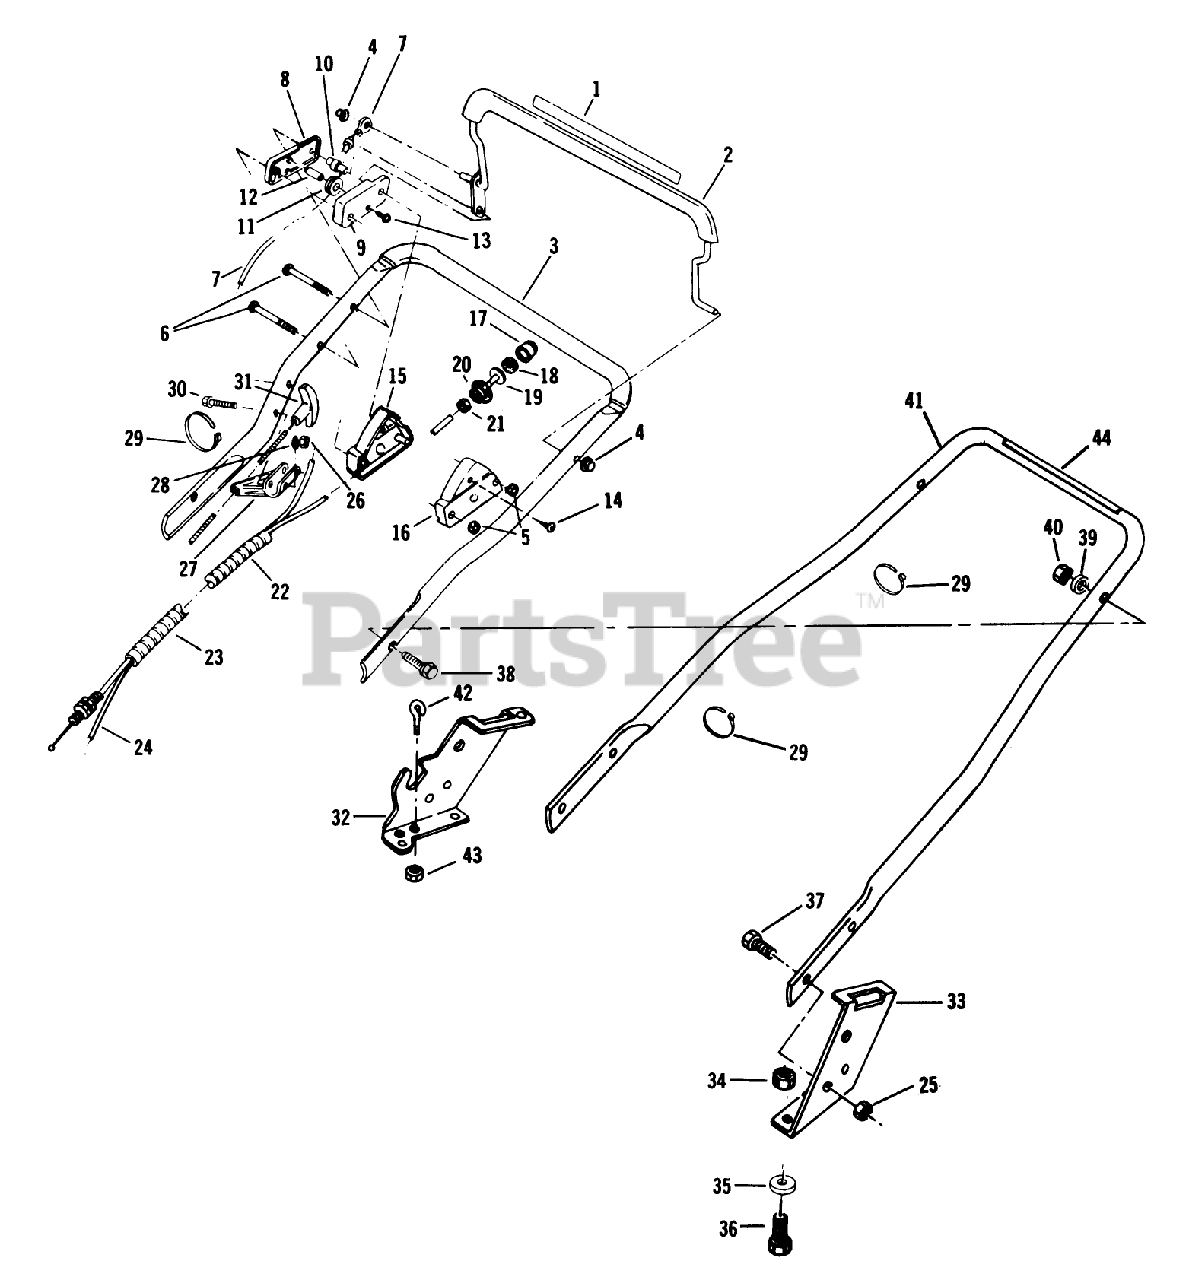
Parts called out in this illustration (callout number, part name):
5	NUT C/LOCK E
10	COLUMN
12	PIN SKF
13	SCREW
14	SCREW LAWRENCE
18	FILTER S
21	LOCKNUT S
25	NUT-JAM, LOCKING
26	LOCKNUT E
28	WASHER
31	HANDLE,STARTER
34	NUT-LOCK F
35	WASHER
37	BOLT
39	WASHER-CURVED
40	NUT-LOCK F
42	BOLT-EYE
43	LOCKNUT E
